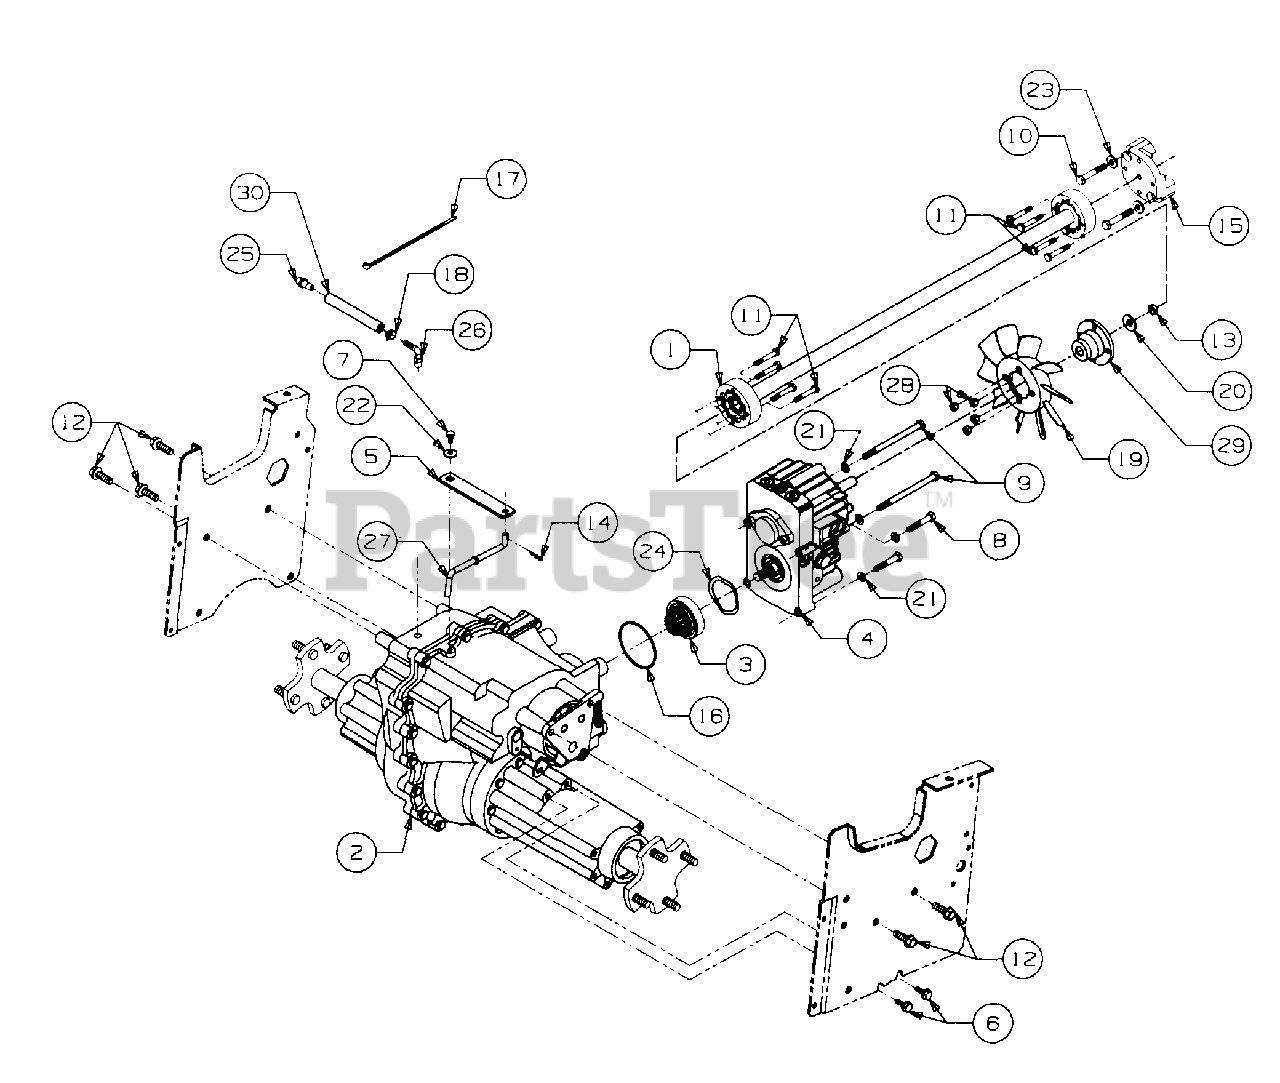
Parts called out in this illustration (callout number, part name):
1	Shaft Assy, Drive, 27.87 Lg
2	Transmission Assembly, Hydro
3	Pinion Assy, Input
4	Pump, Hydrostatic
5	Arm, Hydro Dump
6	Screw, Hex Wash Hd Tapp 5/16-18 x .75
7	Screw, Hex Wash Hd Tapp 1/4-20 x .75 GR5
8	Screw, Hex Cap 5/16-18 x 1.75 GR5
9	Screw, Hex Cap 5/16-18 x 4.5 GR5
10	Screw, Hex Patch, M8-1.25 x 50mm
11	Screw, Hex Patch, 1/4-20 x 1.62 GR5
12	Screw, Hex Wash Hd Tapp 3/8-16 x 1.25
13	Nut, Hex Center Lock Jam, 3/8-24
14	Pin, Internal Cotter, 5/16 Dia x 1.12
15	Adapter, Drive Shaft
16	O-Ring, 2.75 x .103
17	Tie, Self-Clinch Cable
18	Clamp, Hose
19	Fan, 10 Blade Cooling
20	Washer, Bell, .380 x .88 x .063
21	Washer, Lock, 5/16
22	Washer, Bell, .265 x .75 x .062
23	Washer, Flat, .312 x .750 x .119
24	Washer, Spring Wave, 1.96 x 2.44 x .06 1
26	Fitting, Elbow
27	Rod, Hydro Disengagement
28	Nut, Fan, 1/4-20
29	Adapter, Pump
30	Line, Fuel, 7 in. Lg
